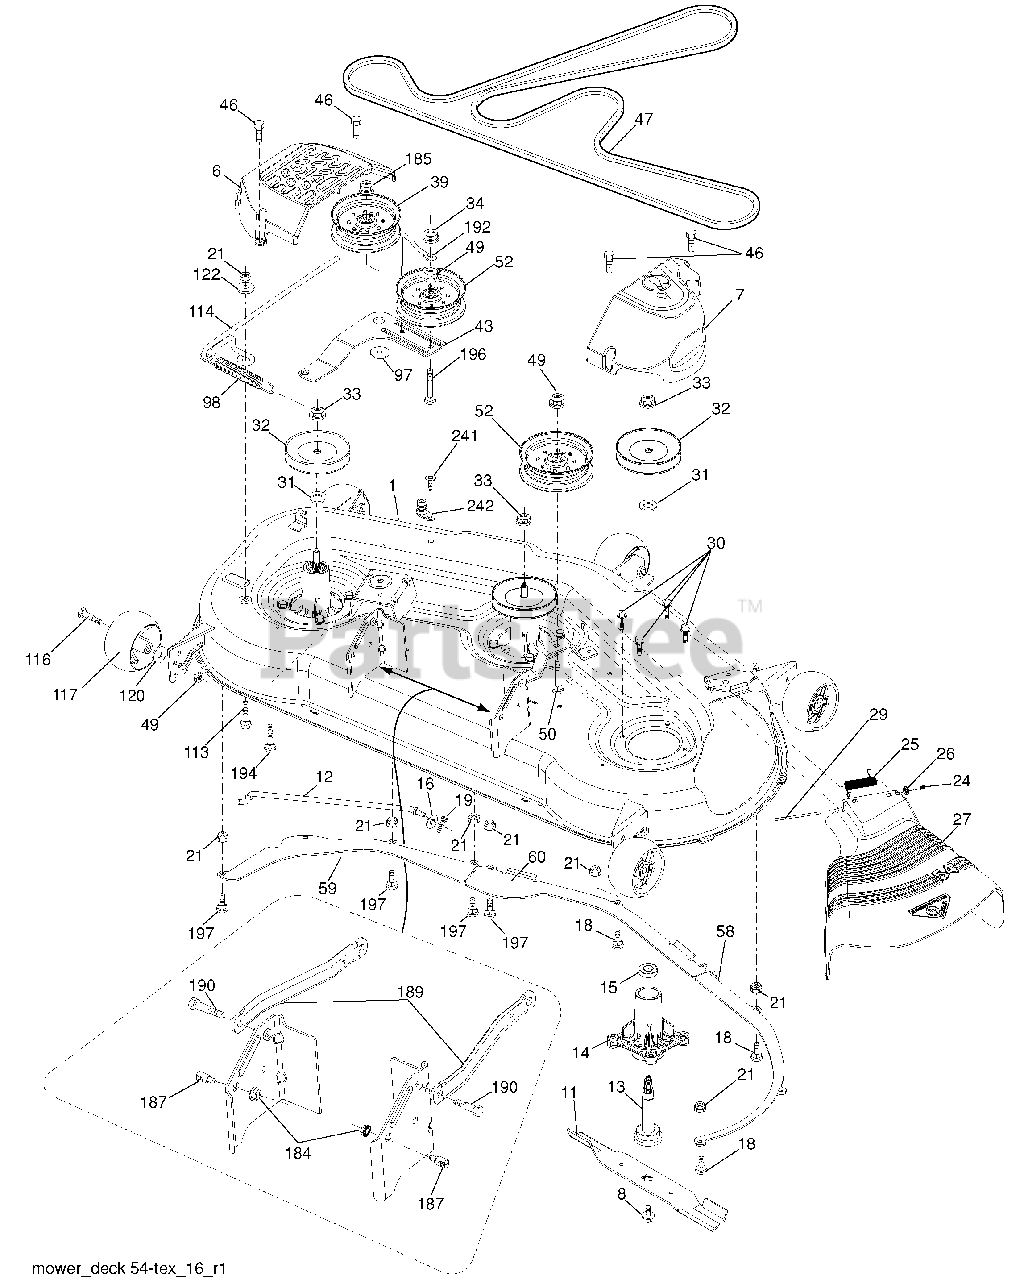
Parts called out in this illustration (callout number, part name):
1	Deck Weldment Mower
6	Cover Mandrel LH
7	Cover Mandrel RH
8	Bolt 7/16 Asm. Blade
11	Blade Discharge/Bagging
11	Blade Mulching
12	Rod-Anti Sway
13	Shaft Asm. w/Lower Bearing
14	Housing, Mandrel
15	Bearing, Ball, Mandrel
16	Washer 13/32 x 13/16 x 12 Ga.
18	Bolt 5/16-18 x 5/8
19	Pin Cotter 5/16 Bow Tie Lock
21	Nut, Crownlock 5/16-18 unc
24	Cap Sleeve
25	Spring, Torsion
26	Nut, Push
27	Deflector Shield
29	Rod, Hinge
30	Screw, Thdrol. Washer Head
31	Washer, Spacer Mower Vented
32	Pulley, Mandrel
33	Nut, Flg. Top Lock
34	Nut Crownlock 3/8-16 unc
39	Pulley, Idler 4.50 HUB
43	Arm, Idler
46	Screw, Thdrol. 1/4-20 x 5/8
47	V-Belt, Mower
49	Nut, Lock Flg. 3/8-16 unc
50	Bolt Rdhd. Sqnk. 3/8-16 unc x 2
52	Pulley Idler
58	Baffle Right
59	Baffle Left
60	Baffle Center
97	Washer Hardened
98	Spring Drive
113	Bolt Rdhd. Sqnk. 5/16-18 x 3/4
114	Rod Tension Relief
116	Bolt, Shoulder
117	Gauge Wheel
120	Washer 13/32 x 1-1/4 x 12 Ga.
122	Bushing Tension Relief
184	Nut Lock Hex Flange 5/16-18
185	Nut Lock Flange 7/16-14 Gr. 5
187	Stud Fastener w/"D" Anti-Rotation
189	Arm Susp. Mower Rear
190	Bolt Shoulder
192	Keeper Belt Idler
194	Bolt Carr. Sqnk. 3/8-16 x 2-1/4
196	Bolt Rdhd. Sqnk. 3/8-16 x 2-1/2 Gr. 5
241	Screw TT #10-32 Flange
242	Washout Port
242	Mandrel Assembly
242	Replacement Mower, Complete
242	Quick Connect Coupling
